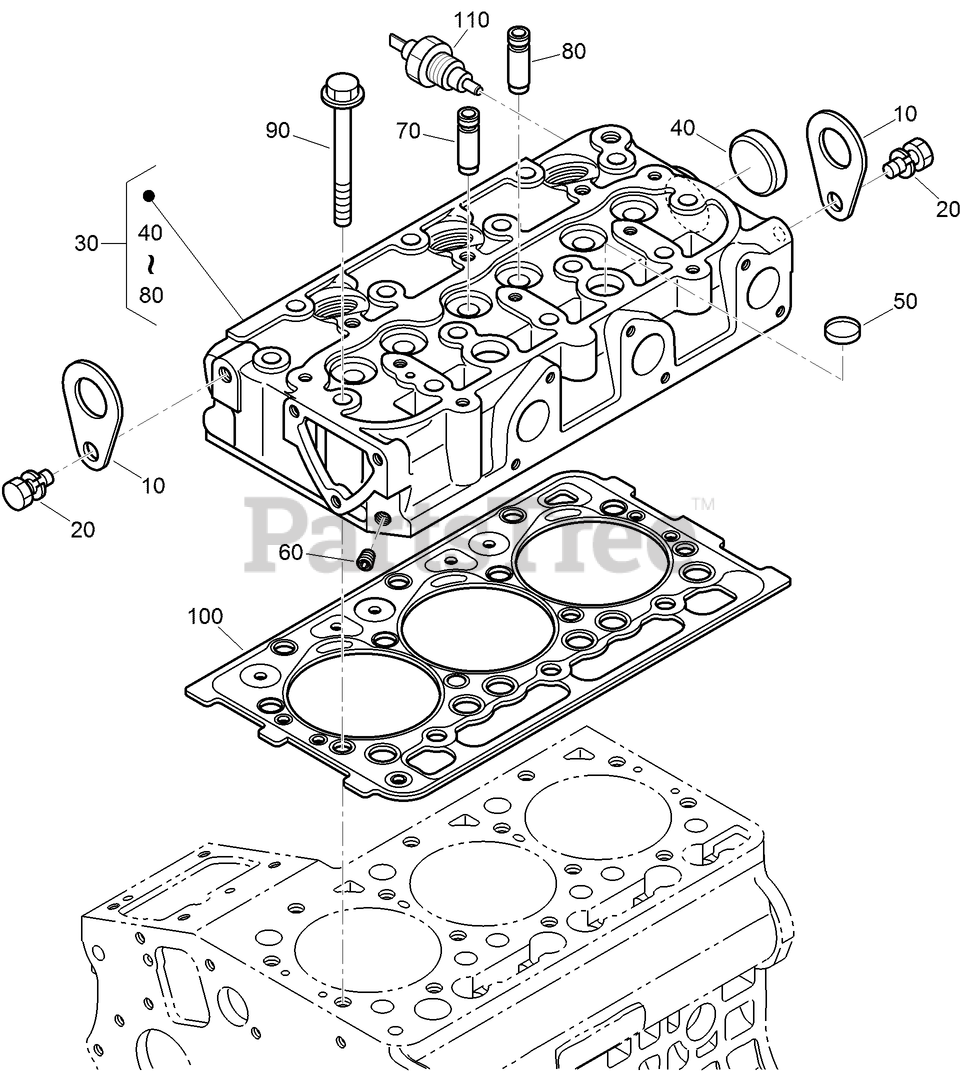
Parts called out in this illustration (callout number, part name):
10	HOOK-ENGINE
30	CYLINDER HEAD ASM
40	CAP-SEALING
50	CAP-SEALING
70	GUIDE-VALVE, INLET
80	GUIDE-VALVE, EXHAUST
90	BOLT-HEAD, CYLINDER
100	GASKET-HEAD, CYLINDER
110	SWITCH-OIL
